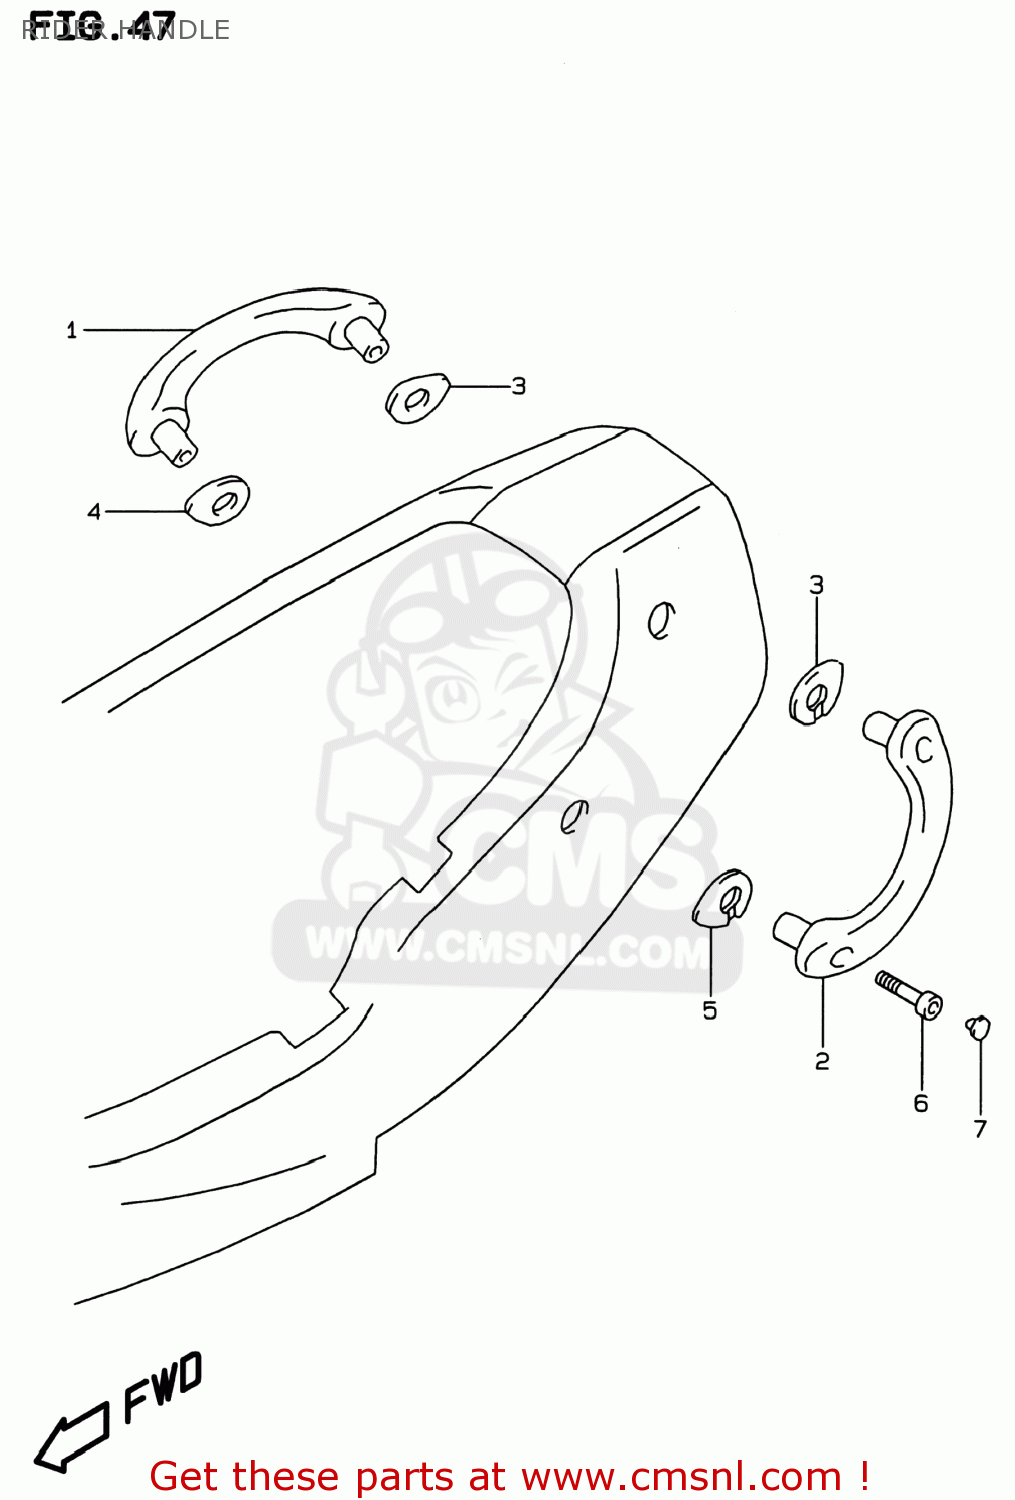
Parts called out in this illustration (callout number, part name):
1	HANDLE,PILLION RIDER,R
2	HANDLE,PILLION RIDER,L
3	CUSHION,PILLION HANDLE UPR
4	CUSHION,PILLION HANDLE LWR,R
5	CUSHION,PILLION HANDLE LWR,L
6	BOLT
7	CAP(OD:14.5)
